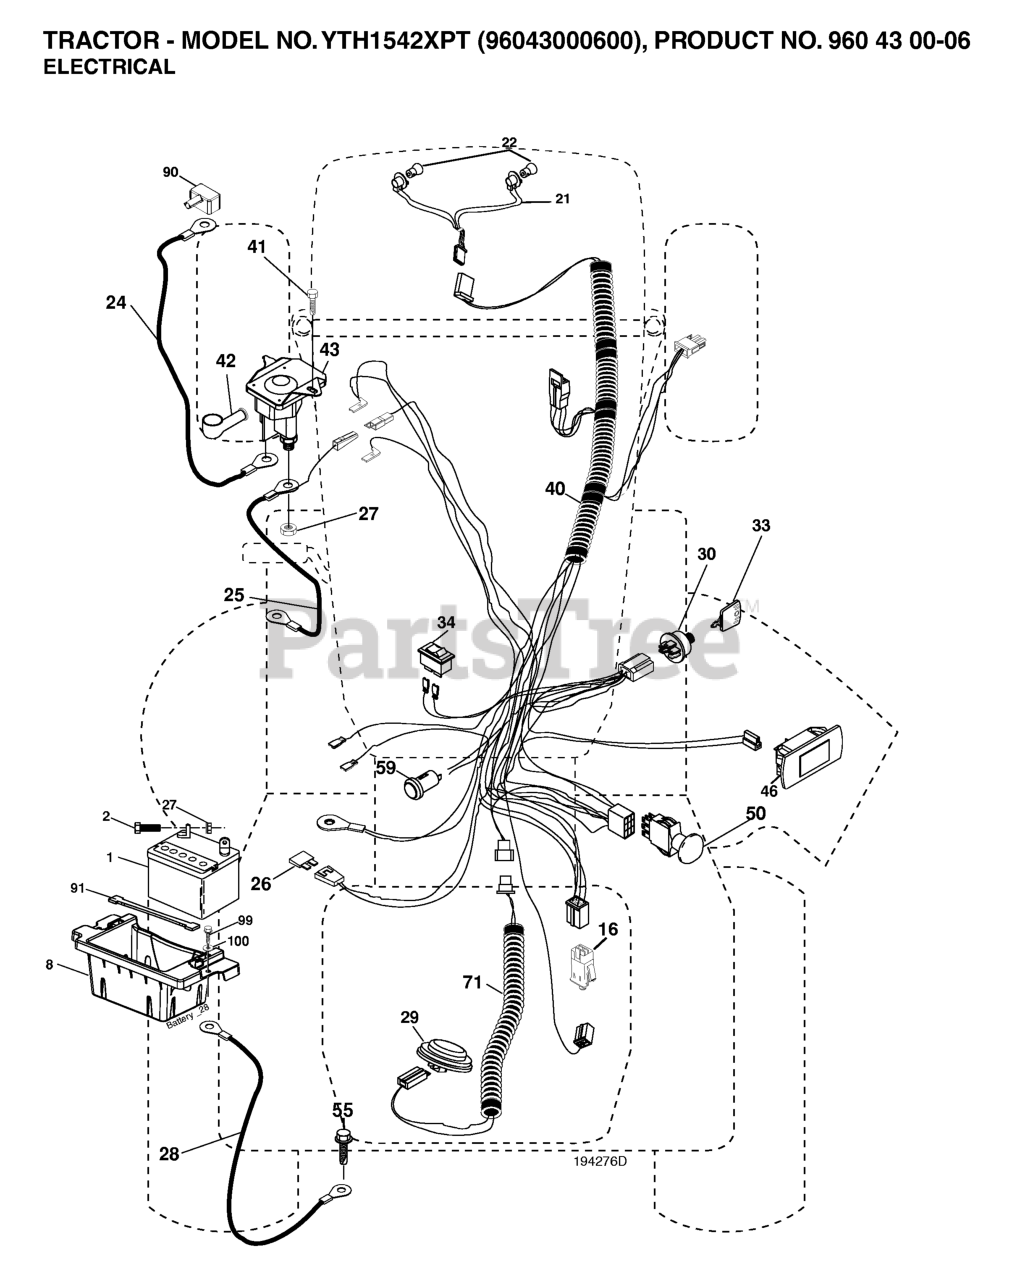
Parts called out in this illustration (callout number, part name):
1	BATTERY 12V .35 AMP
2	BOLT.HEX.1/4.X.3/4.DICHROMATE
8	BOX.BATTERY.MOUNT.FRONT.LT
16	SWITCH INTERLOOK PUSH-IN
21	HARNESS ASSY LIGHT
24	CABLE.BATT.POS.WIRE.TG.DA SOL
25	CABLE.START.RED.17.5".
26	FUSE 20AMP
27	NUT
28	CABLE GROUND 6 GA 21" 90T BLK
29	SWITCH.SEAT.DELTA.OPC.
30	SWITCH.IGN.DELTA.W.LGH.ROS
33	KEY MLD GEN DELTA
40	HARNESS-CHASSIS SUB
41	SCREW
42	TERMINAL COVER
43	SOLENOID.W/BRASS.PLUNGER
46	GAUGE.SERVICEMINDER.HR
50	RP.PTO.SWITCH.8 TERMINAL.BLACK
55	SCREW.THDROL.5/16-18X3/4.TTY
59	OUTLET.12-VOLT
71	HARNESS.IGN.DASH.HUQ/PRED.OUTL
90	COVER TERMINAL
91	STRAP.BATTERY.MOUNT.FRONT(2 2)
99	SCREW HEXWSHR 1/4-20X3/4
